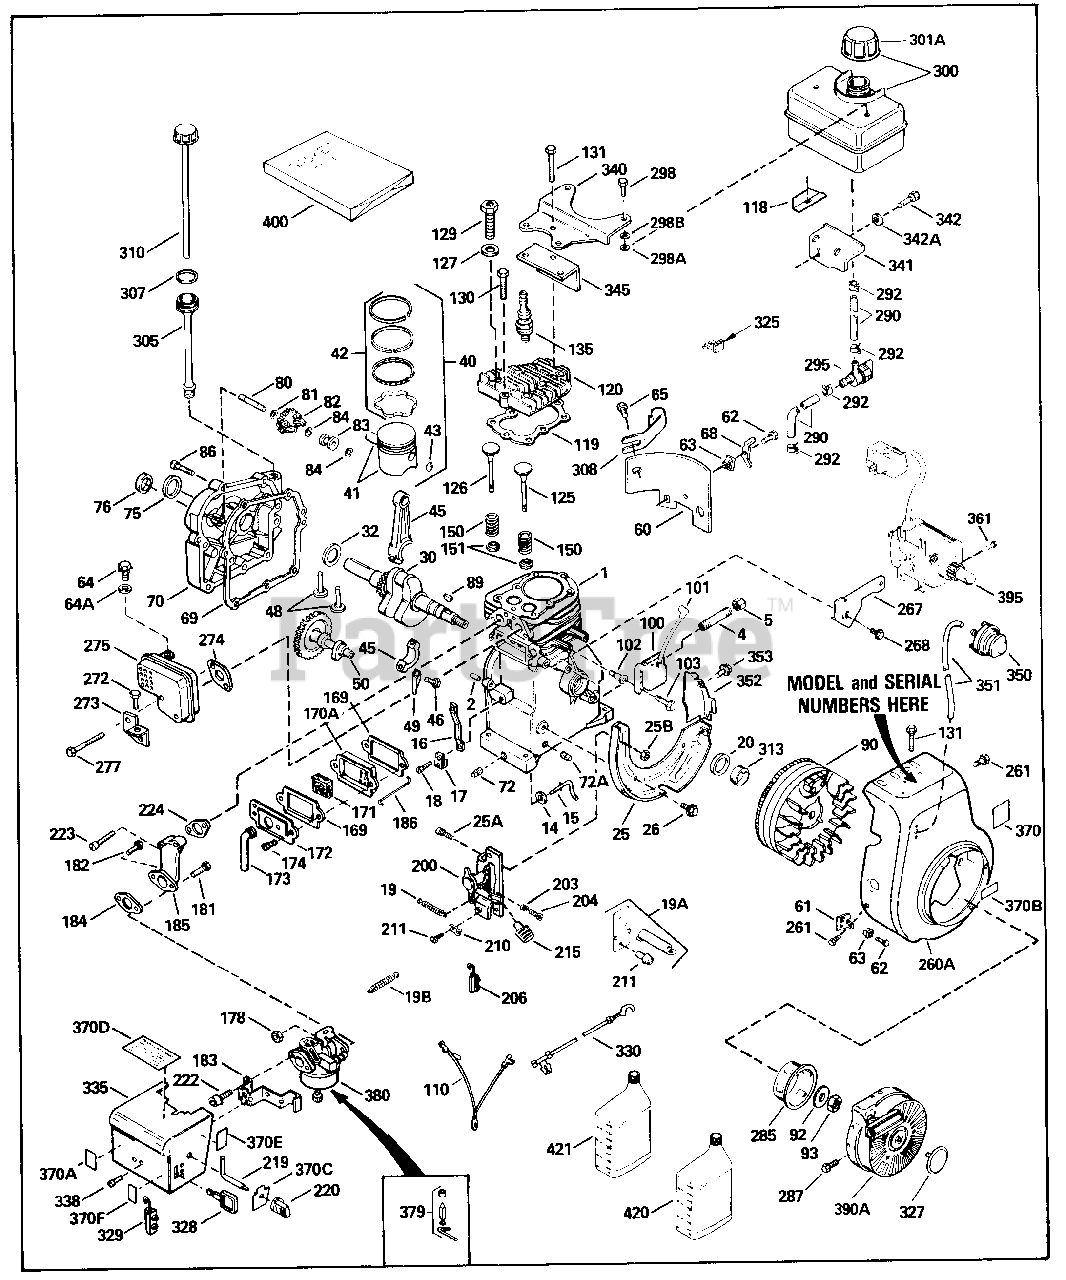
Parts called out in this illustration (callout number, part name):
1	"Cylinder (Incl. 2,20,72 & 72A) 2-5/8" Bore
2	Dowel Pin
4	Extension, Oil drain
5	Cap, Oil drain Extension
14	Flat Washer
15	Rod, Governor
16	Lever, Governor
17	Clamp, Governor lever
18	Screw, 8-32 x 5/16"
19	Spring, Extension
20	Seal, Oil
25	Baffle, Blower housing
25A	Screw, 8-32 x 1/2"
25B	Lock Nut, 8-32
26	Screw, 1/4-20 x 5/8"
30	Crankshaft
40	Piston, Pin & Ring Set (Std.) (2-5/8"
40	Piston, Pin & Ring Set (.010" OS)
40	Piston, Pin & Ring Set (.020" OS) (In cl. 41, 42 & 43)
41	Piston & Pin Assembly (Std.) (Incl. 4 3)
41	Piston & Pin Assembly (.010" OS) (Inc l. 43)
41	Piston & Pin Assembly (.020" OS) (Inc l. 43)
42	Ring Set (Std.) (2-5/8" Bore)
42	Ring Set (.010" OS)
42	Ring Set (.020" OS)
43	Piston Pin Retaining Ring
45	Rod Assy., Connecting (Incl. 46 & 49)
46	Bolt, Connecting rod
48	Valve Lifter
49	Dipper, Oil
50	Camshaft (Extended)
60	Blower Housing Extension
61	Bracket, Grommet mounting
62	Screw, 8-32 x 3/8"
63	Breather Tube Grommet
64	Screw, T-30, 1/4-20 x 1/2"
64A	Washer, Flat
65	Screw, 10-24 x 1/2"
69	* Gasket, Cylinder cover
70	Cover, Cylinder (Incl. 75, 76 & 80)
75	Oil Seal
76	Camshaft Seal
80	Shaft, Mechanical governor
81	Washer, Flat
82	Gear, Governor (Incl. 81)
83	Spool, Governor
84	Retaining Ring
86	Screw, 1/4-20 x 1-1/4"
89	Flywheel Key (also available in Packa ged Part #740007B)
90	Flywheel (w/ring gear)
92	Washer, Belleville
93	Nut, Flywheel
100	Solid State Ass'y.
101	Cover, Spark plug
102	Stud, Solid state mounting
103	Screw, Torx T-15, 10-24 x 1"
110	Ground Wire
119	* Gasket, Cylinder cover
120	Head, Cylinder (Incl. 131)
125	Exhaust Valve (Std.) (Incl. 151)
125	Exhaust Valve (1/32" OS) (Incl. 151)
126	Intake Valve (Std.) (Incl. 151)
126	Intake Valve, (1/32" OS)(Incl. 151)
127	Washer, Flat
129	Screw, 5/16-18 x 1-1/2"
130	Screw, 5/16-18 x 1-1/2"
131	Screw, 5/16-18 x 2"
135	Resistor Spark Plug - RJ17LM
150	Spring, Valve
151	Cap, Valve spring
169	* Gasket, Valve cover
170A	Breather Body
171	Element, Valve body
172	Cover, Breather
173	Breather Tube
174	Screw, 10-24 x 1/2"
178	Nut & Lock Washer 1/4-28
181	Screw, 1/4-28 x 7/8"
182	Screw, 1/4-28 x 1-11/16"
183	Bracket, Choke
184	* Gasket, Carburetor
185	Pipe, Intake
186	Link, Governor-to-throttle
200	Control Bracket (Incl. 25A,25B,203,20 4 ,206) NOTE: In original productio nthe speed control assembly is rivete d to the blower housing baffle (33342 ). Replacement speed control includes screws (650139) and nuts (30322) for mounting. Replacement b
203	Spring, Compression
204	Screw, 5-40 x 7/16"
206	Terminal Ass'y. (Use as required)
215	Control Knob
219	Rod, Choke
220	Control Knob
222	Screw, 10-32 x 1/2"
223	Screw, 1/4-20 x 1-19/32"
224	* Gasket, Intake
260A	Blower Housing
261	Screw, 1/4-28 x 7/16"
267	Bracket, Hold down
268	Screw, 10-24 x 9/16"
272	Screw, 10-24 x 3/8"
273	Bracket, Carburetor cover
274	* Gasket, Exhaust
275	Muffler (Incl. 274)
277	Screw, 1/4-20 x 2-1/2"
285	Cup, Starter
287	Screw, 8-32 x 1/2"
290	Fuel Line (8.62") ed)
290	Fuel Line (16")(40cm) Use as required
290	Fuel Line (32")(80cm) Use as required
292	Fuel Line Clamp
298	Screw, 1/4-15 x 7/8"
300	Fuel Tank (Incl. 292 & 301) (2 Quart)
301A	Fuel Cap (Red 1-1/2" ID) also availab le in Packaged Part #740005B
301A	Fuel Cap (Use as required)
301A	Fuel Cap (Red)
305	Oil Fill Tube
307	"O" Ring
308	Fill Tube Clip
310	Dipstick
313	Spacer, Flywheel key
327	Starter Plug
328	Ignition Key
329	Terminal Assy.
330	Ground Wire
335	Carburetor Cover
338	Screw, 8-32 x 5/16"
340	Fuel Tank Bracket
341	Fuel Tank Bracket
342	Screw, T-30, 1/4-20 x 1/2"
342	Screw, 1/4-20 x 5/8" Use as required
342	Screw, 1/4-20 x 7/16" Use as require d
342	Screw, 1/4-20 x 11/16" Use as requir ed
342A	Washer, Flat
345	Baffle, Heat
350	Primer Assy.
351	Line, Primer
352	Extension, Baffle
353	Screw, 8-32 x 1/2"
370B	Decal, Primer
370C	Decal - Speed Control & Choke
370D	Decal, Instruction
379	Inlet Needle Seat & Clip Assy.
380	Carburetor (Incl. 184) (Refer to Divi sion 5 SectionA, page A1-2 or Fiche 1 4A, Grid E-1for breakdown)
390A	Starter, Rewind Refer to Division 5, SectionC, page 34 or Fiche 14A, Grid G-9 for breakdown)
400	* Gasket Set (Incl. items marked *)
420	SAE 30 4-Cycle Engine Oil (Quart)
421	SAE 5W30 4-Cycle Engine Oil - Quart - Winter
